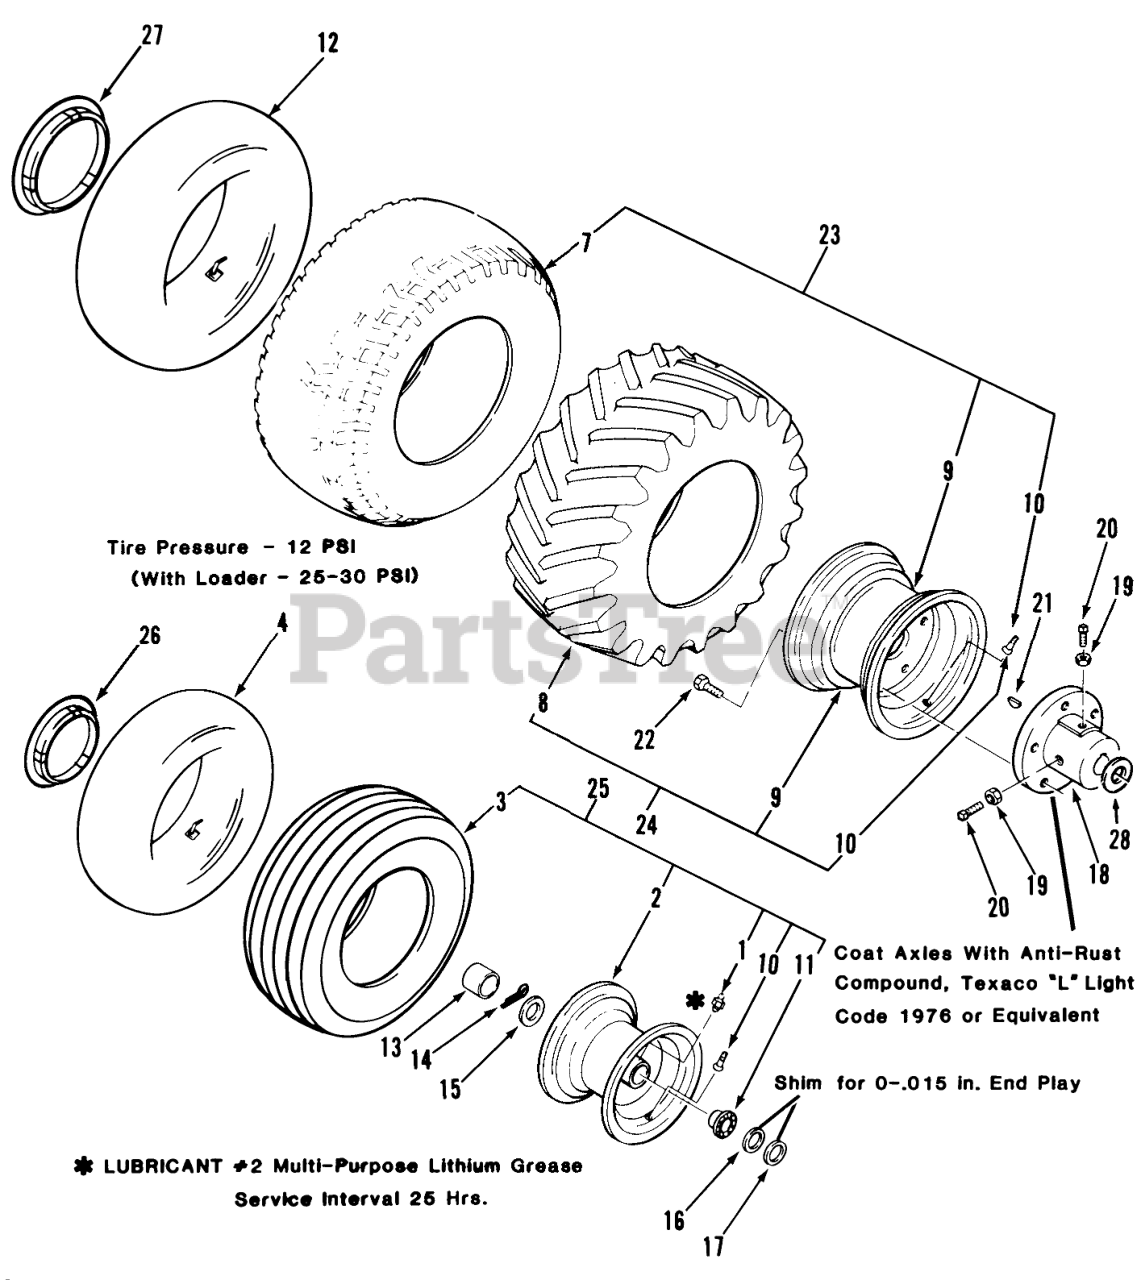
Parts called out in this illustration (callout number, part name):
1	ZERK-GREASE
2	Front Wheel (includes Item 1,11) 312-A
2	Front Wheel (includes Item 1,11) 418-8,418-A
2	Front Wheel (includes Item 1,11) 418-C
2	Front Wheel (includes Item 1,10,11)308-8,310-8
2	Front Wheel (includes Item 1,10,11)312-8
2	Front Wheel (includes Item 1,10,11)414-8,416-8
3	TIRE15 X 6.00-6
3	TIRE TURF SAVER 16X6.50-8
3	Front Tire 15x6.00-6 Rib Tread 308-8
4	TUBE-INNER
7	TIRE 22 X 9.00-12
7	Engine
7	Rear Tire 23 x 10.50-12 GT-1800 Only
7	TIRE 22 X 7.50-12
7	Tire
8	Tire-Cleat, Rear
9	WHEEL
9	RIM ASM
10	VALVE
11	BEARING-WHEEL
11	BEARING-RADIAL FLNGE
12	INNER TUBE
12	TUBE-INNER
12	Rear Tube
12	Tube Cleat Tires
13	HUB CAP-FLAT BLACK
13	CAP-HUB
13	HUBCAP
14	COTTER PIN-4
15	WASHER-WHEEL
15	WASHER WHEEL
16	WASHER
17	WASHER-SHIM
18	Hub Rear
18	Hub-Rear
19	Nut
20	Screw-Set
21	KEY-WOODRUFF
21	WOODRUFF KEY
22	Lug Nut
23	Rear Wheel & Tire Assy 312-A
23	Rear Wheel & Tire Assy w/tube 417-A
23	Rear Wheel & Tire Assy w/tube 418-C
23	Rear Wheel & Tire Assy 308
23	Rear Wheel & Tire Assy 310
23	Rear Wheel & Tire Assy 312
23	Rear Wheel & Tire Assy 414
23	Rear Wheel & Tire Assy 416
24	ASSY WHEEL & TIRE
25	ASSY WHEEL & TIRE
25	Front Wheel & Tire Assy w/tube 418-8,418-A
25	Front Wheel & Tire Assy w/tube 418-C
25	Front Wheel & Tire Assy 308-8
25	Front Wheel & Tire Assy 310
25	Assy-Wheel & Tire Front
25	Front Wheel & Tire Assy 414, 416
26	Chrome Hub Cap 6"Front w/ Clips 111938
26	8" HUB CAP WITH LOGO
27	Chrome Hub Cap 12" Rear w/ Clips 111938
28	WASHER-THRUST
